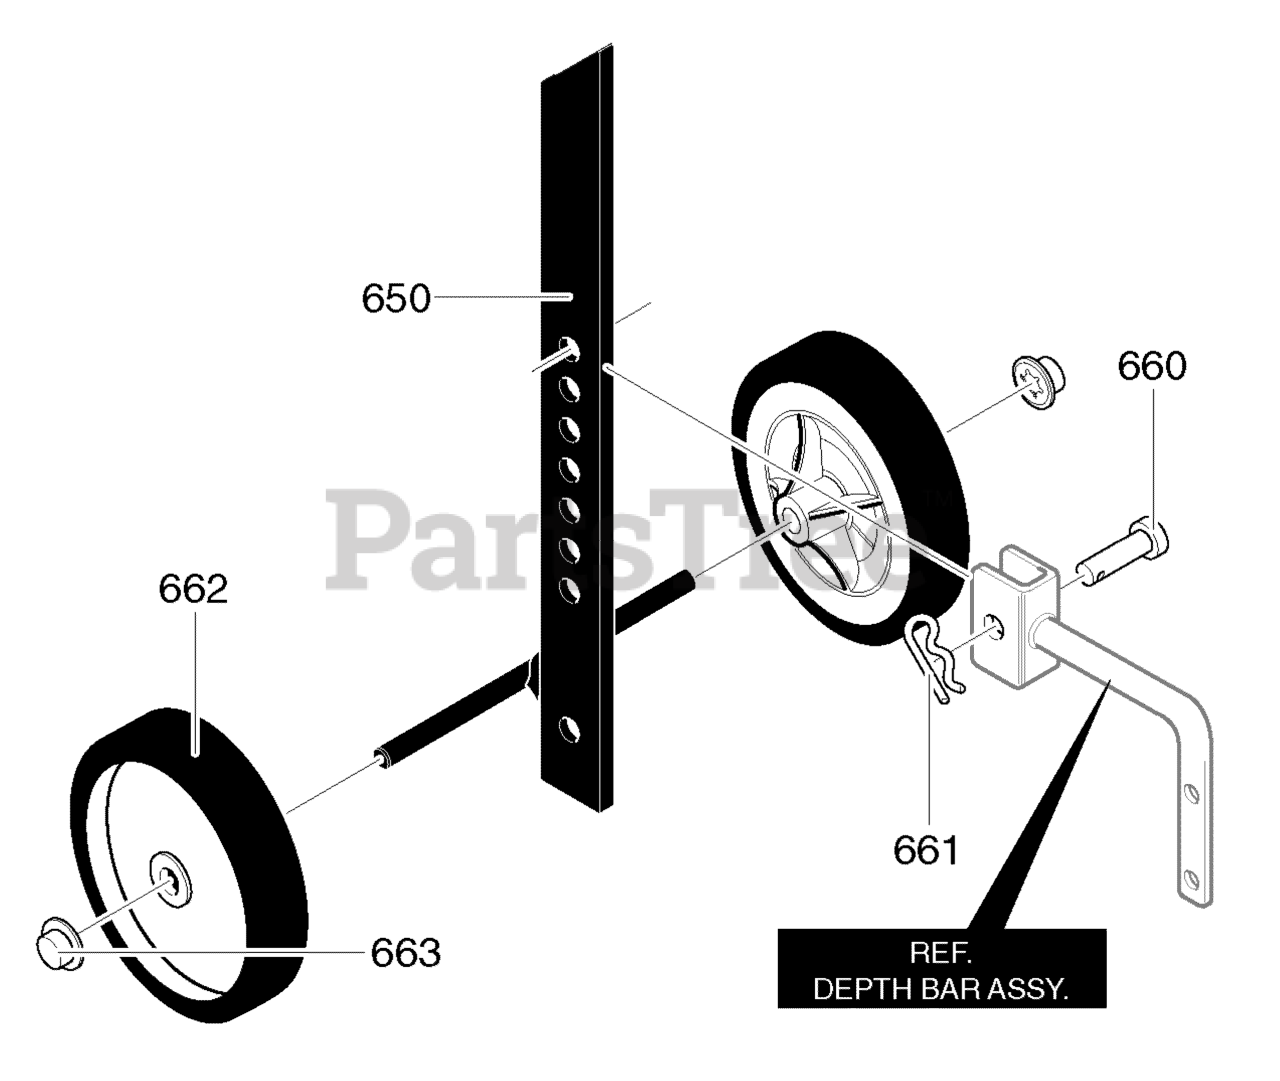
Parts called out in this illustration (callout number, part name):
650	WHEEL SUPPORT ASSEMBLY
660	PIN, Clevis
662	TIRE & RIM
663	NUT, Push on
